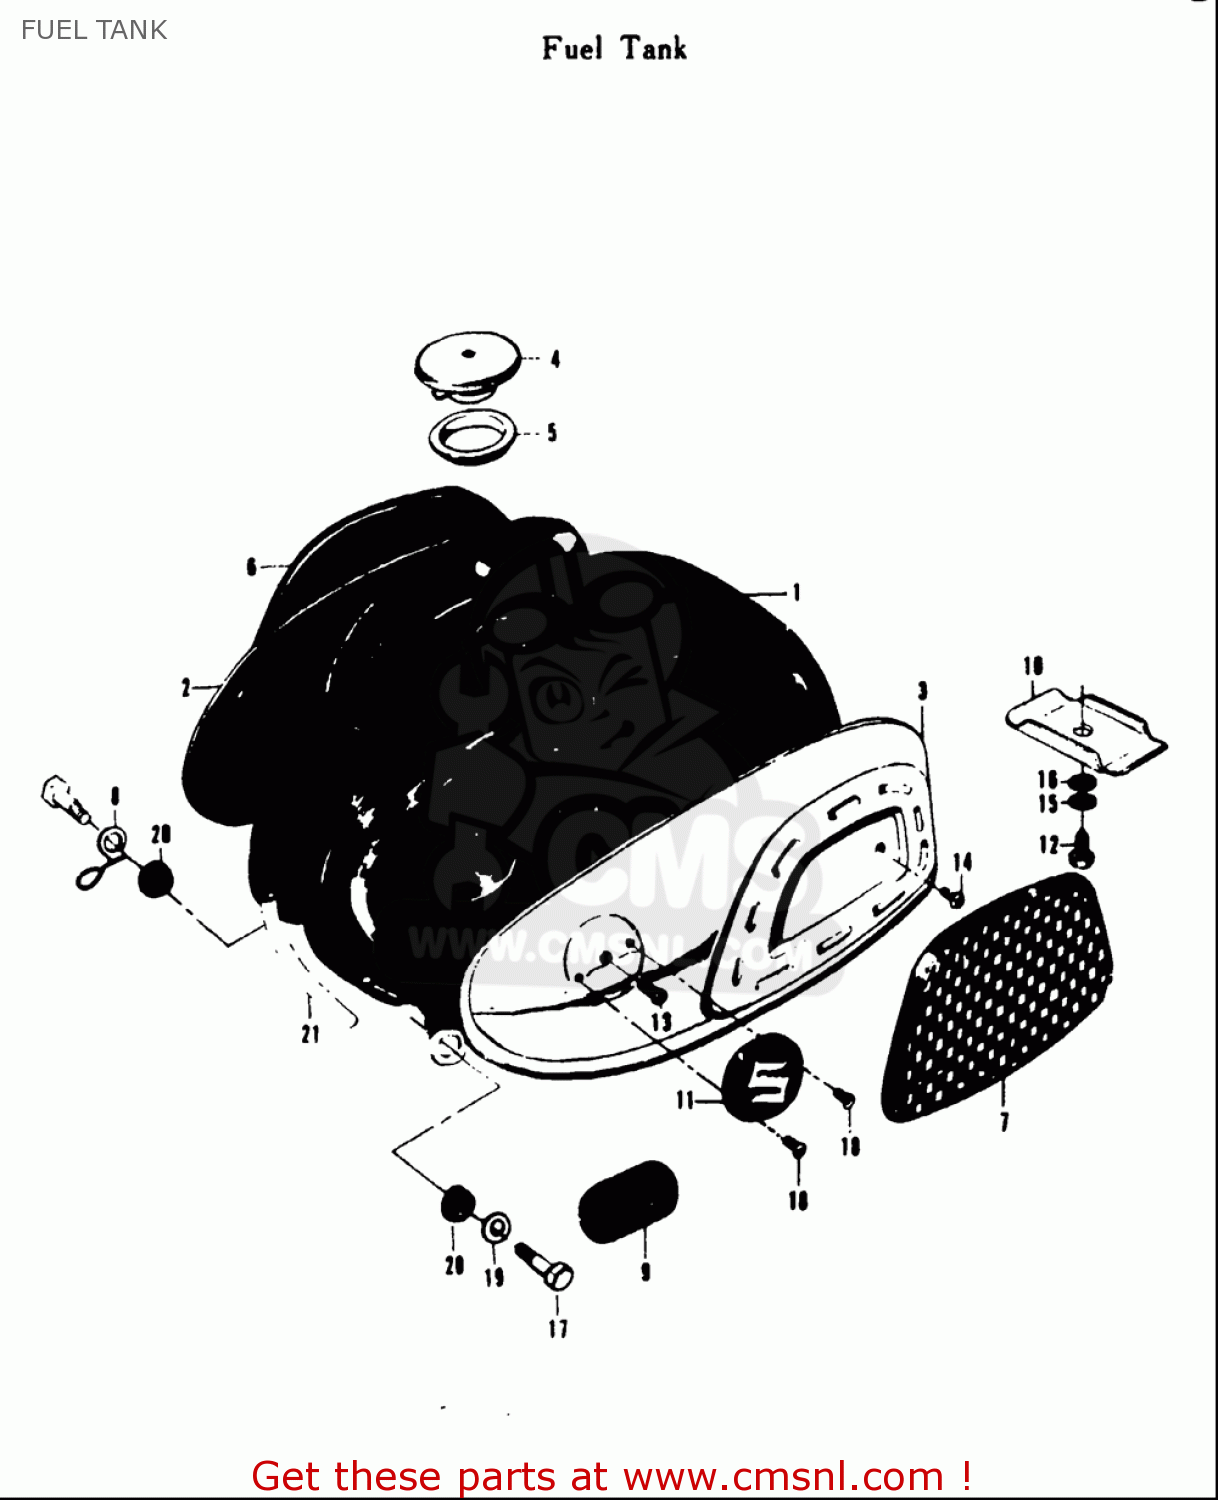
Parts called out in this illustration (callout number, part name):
12	BOLT
14	SCREW(5X6)
15	WASHER,LOCK
16	WASHER
19	WASHER(12.5X26X1.6)
